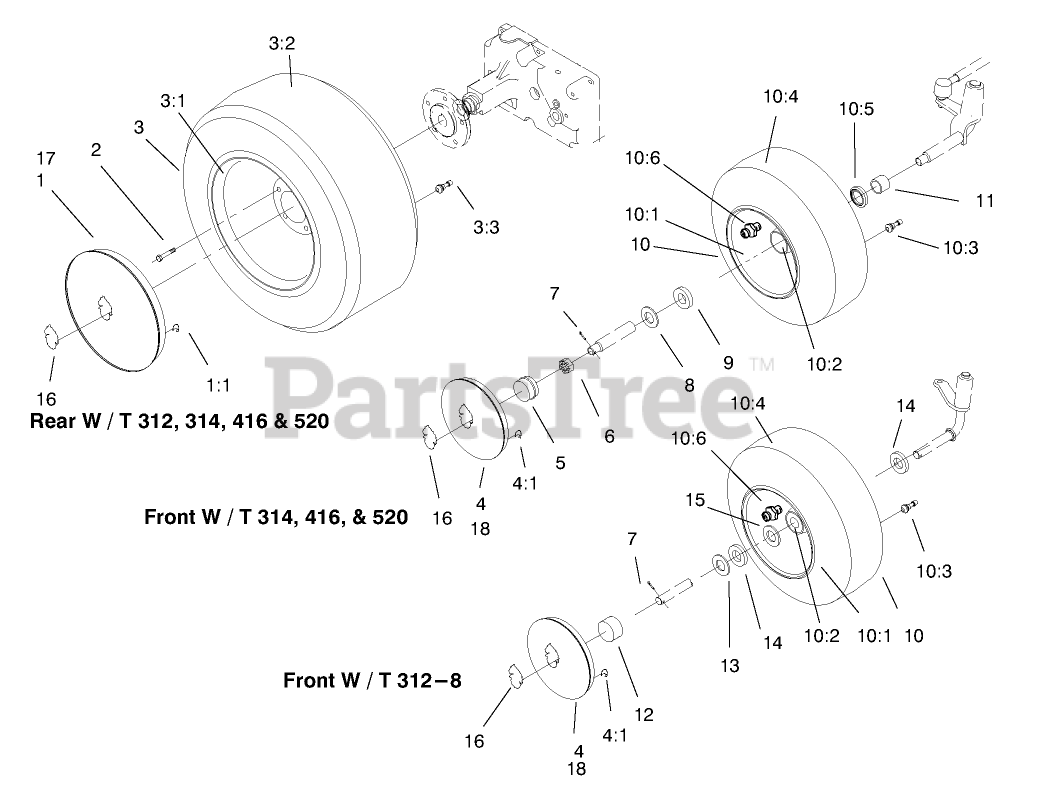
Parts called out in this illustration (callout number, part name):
2	BOLT-LUG
3	ASM-Wheel Tire
3:1	WHEEL
3:3	VALVE
7	PIN-COTTER
10:1	WHEEL ASM
10:2	BEARING-WHEEL
10:3	VALVE
10:4	TIRE (16 X 6.5-8) 2-PLY -2 WHEEL AXEL
10:6	ZERK-GREASE
12	HUBCAP
13	WASHER WHEEL
14	WASHER
15	WASHER-SHIM
